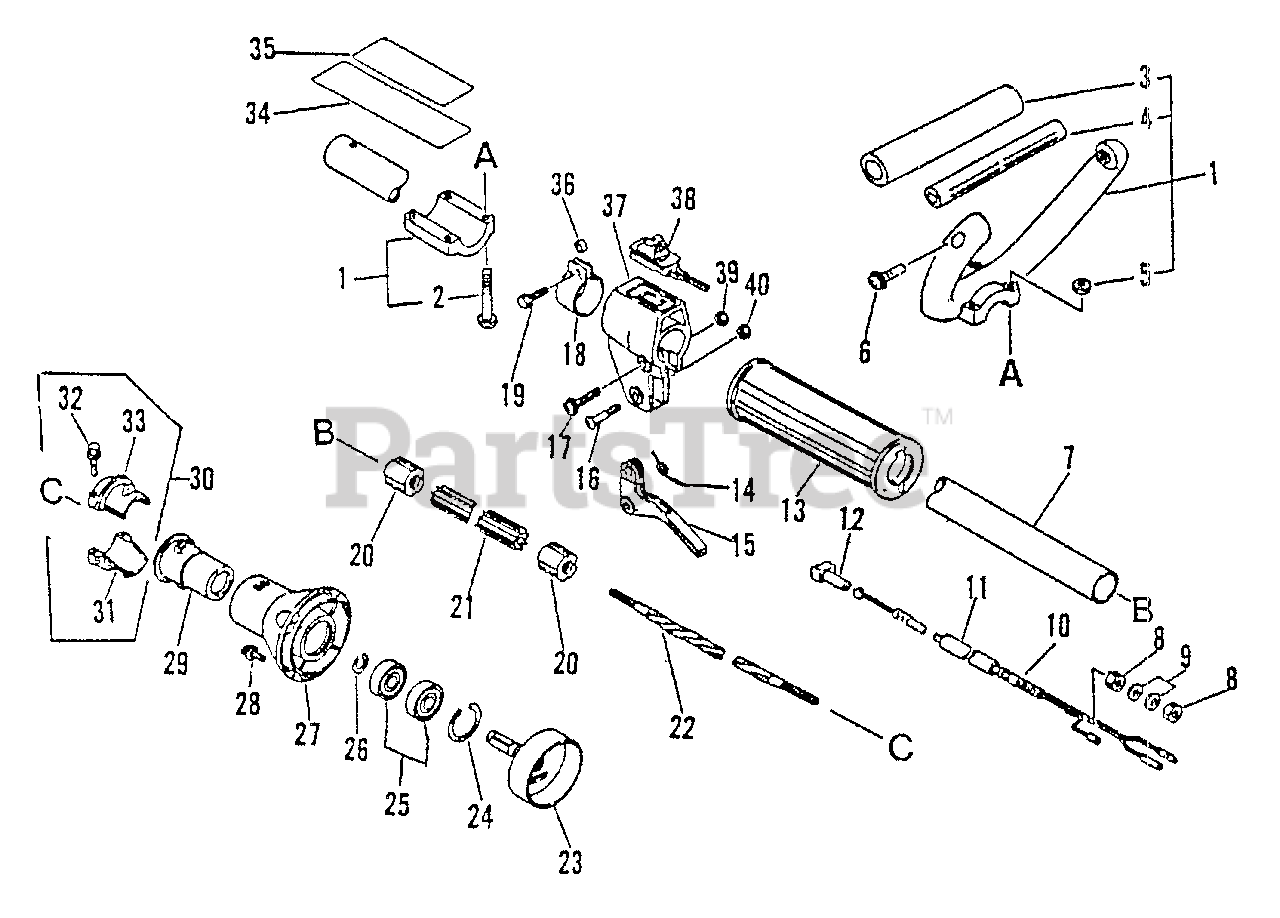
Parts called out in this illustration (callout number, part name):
1	LOOP HANDLE ASSY
2	SCREW - 5X35
3	GRIP, HANDLE
6	SCREW - 5X30
7	MAIN PIPE ASSY
9	WASHER - 6
10	CABLE, THROTTLE
11	TUBE - VINYL
12	GUIDE, CABLE
13	GRIP, HANDLE
14	SPRING, TRIGGER
15	TRIGGER, THROTTLE
16	SCREW - 5X30
17	SCREW - 5X30
19	BOLT - 5X18
21	LINER - FLEXIBLE
22	DRIVESHAFT - FLEXIBLE
23	DRUM, CLUTCH
24	RING, RETAINING - 28
25	BEARING, BALL - 6001
26	RING, RETAINING - 12
27	FLANGE, DRIVESHAFT HOUSING
28	SCREW - 5X16
30	HOLDER KIT
31	CLAMP, MAIN PIPE
32	BOLT - 5X25
33	CLAMP, MAIN PIPE - UPPER
34	LABEL - CAUTION
35	LABEL - CAUTION
37	BRACKET, THROTTLE CONTROL
38	IGNITION SWITCH ASSY
40	LOCKNUT - 5
